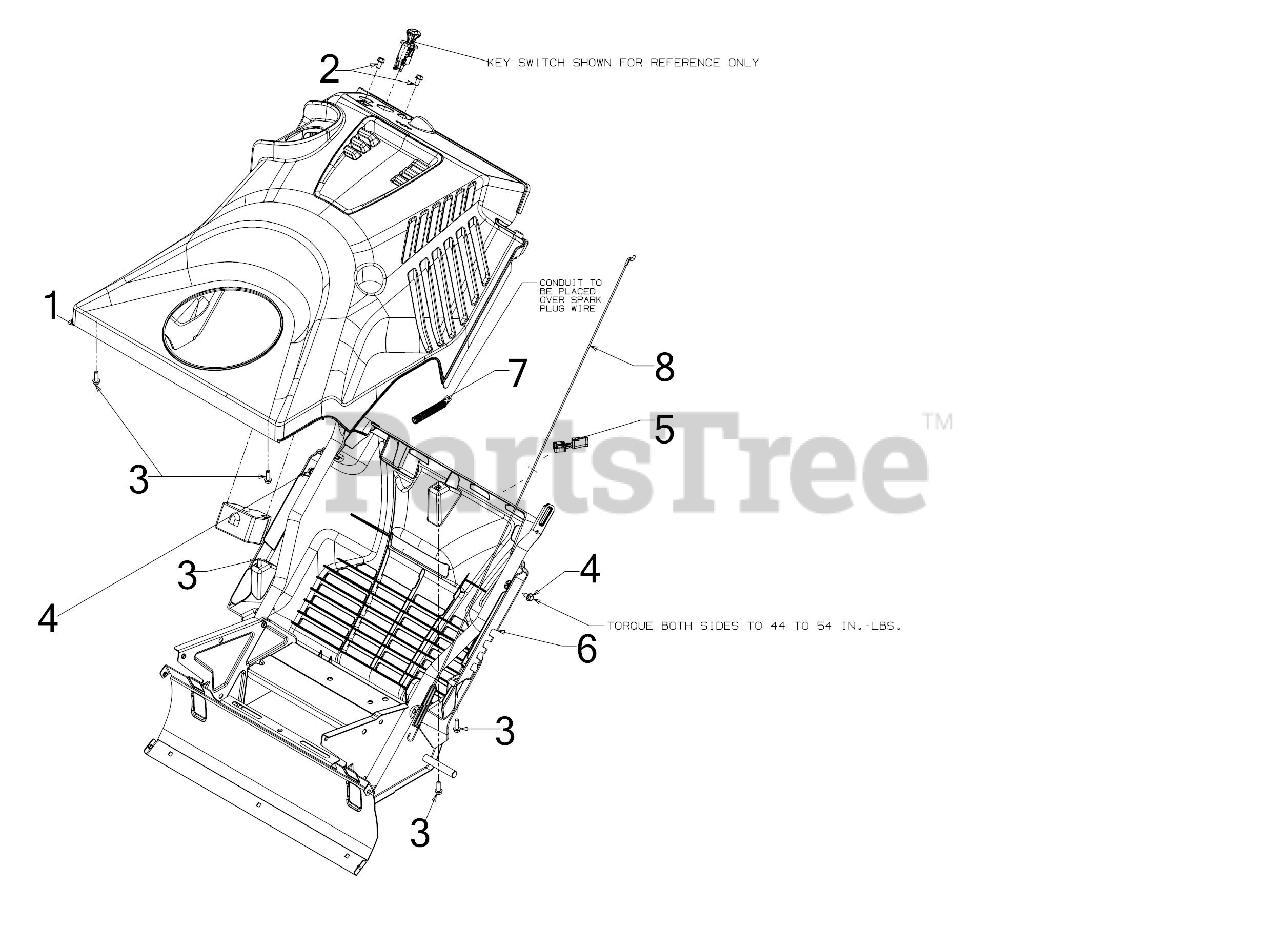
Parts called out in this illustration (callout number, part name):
1	COVER ASSEMBLY
2	HEX SCREW 1/4-15 x .50
3	SCREW 1/4-15 x .750
4	SCREW 1/4-20X.625
5	CHOKE EXTENION LEVER
6	BOTTOM COVER
7	CONVOLUTED CONDUIT
8	AUGER CLUTCH CABLE 37.05"
